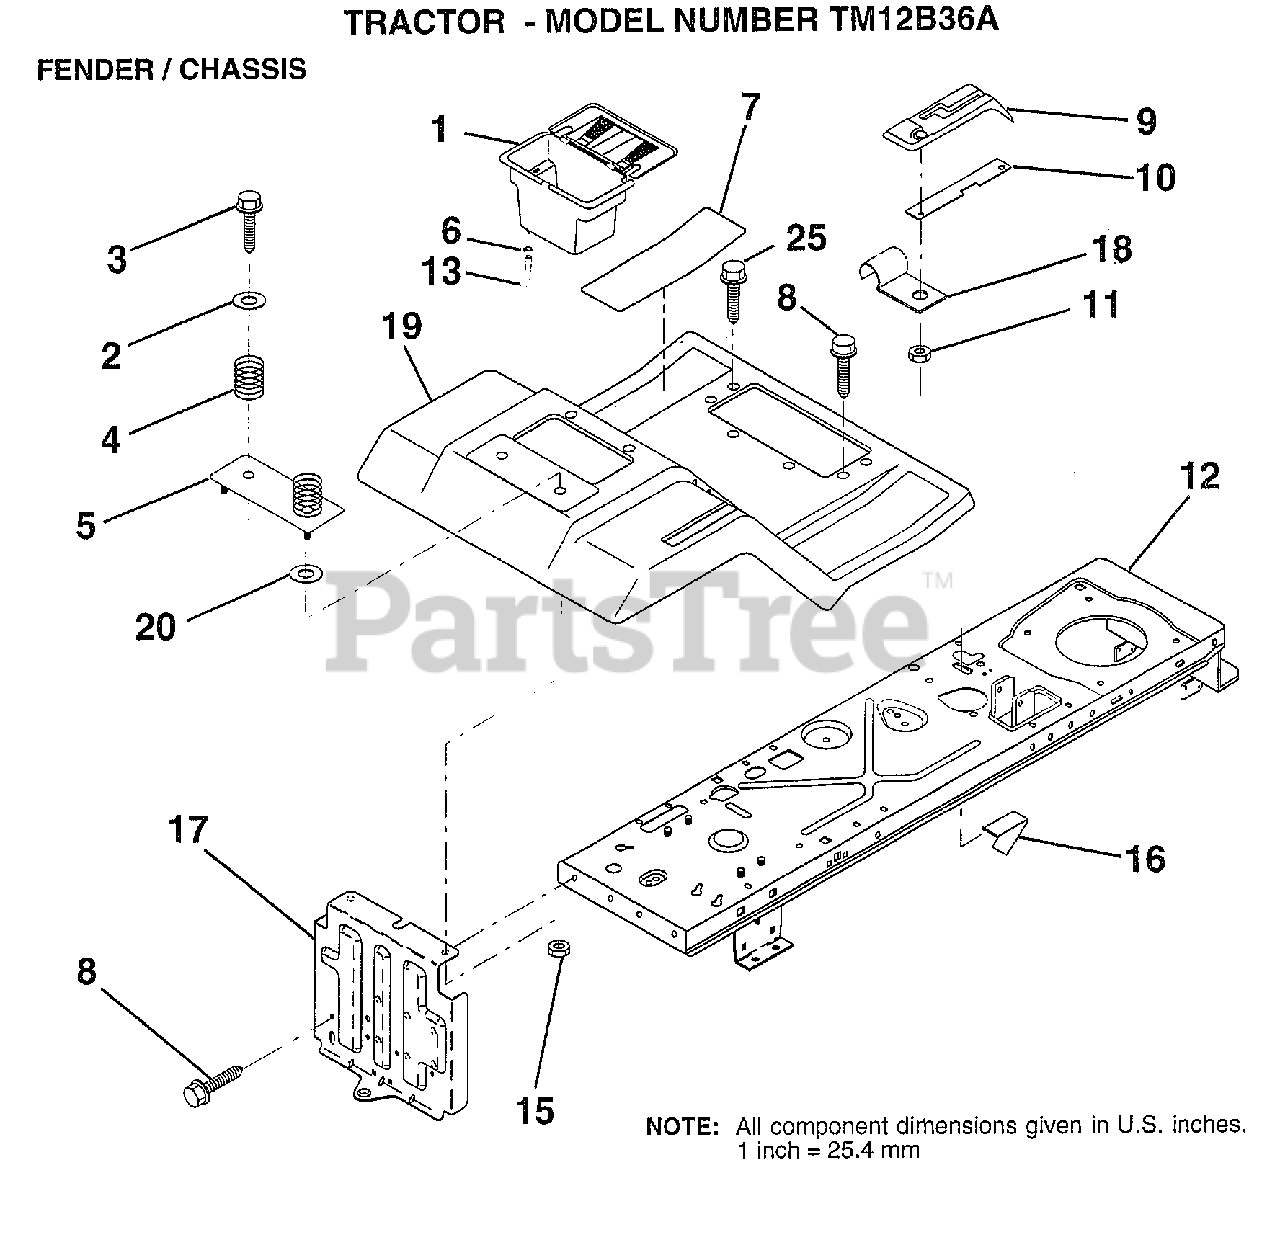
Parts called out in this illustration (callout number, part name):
1	"CASE,BATTERY.MECH"
2	WASHER
3	SCREW
4	SPRING COMPRESSIO
5	BTRY FENDER PLATE
6	HOSE CLAMP T
7	PAD FOOTREST
8	SCREW
9	"CONSOLE,SHIFT CON"
10	PLATE LOCK SHIFT
11	NUT
12	CHASSIS.WELD.ASM.
13	TUBE T
15	NUT HXKEP 1/4X20
17	DRAWBAR ASM LR
18	"CLIP,INSULATOR"
19	FENDER/FOOT MS505
25	SCREW
